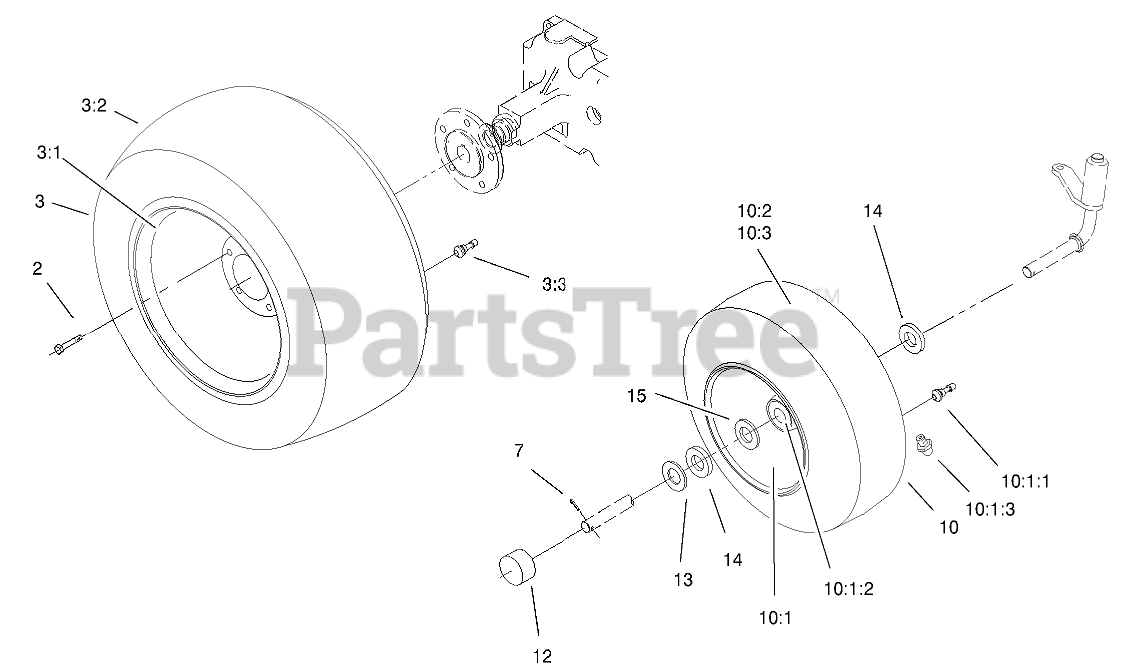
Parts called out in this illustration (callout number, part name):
2	BOLT-LUG
3:1	WHEEL
3:2	Tire-23 X 950-12 (only on: 73449)
3:2	Tire-23x8.50-12 2ply (only on: 73429)
3:3	VALVE
7	PIN-COTTER
10:1	ASM-Wheel w/Zerk (only on: 73449)
10:1	Ass-y-Wheel (only on: 73429)
10:1:1	Valve-Tubeless Tire (only on: 73449)
10:1:2	Bearing Wheel (only on: 73449)
10:1:3	Zerk-Grease (only on: 73449)
10:2	Tire-15 X 6.00-6 (only on: 73429)
10:3	Tire (only on: 73449)
12	CAP-HUB
13	WASHER-PLAIN
14	WASHER
15	WASHER-SHIM
